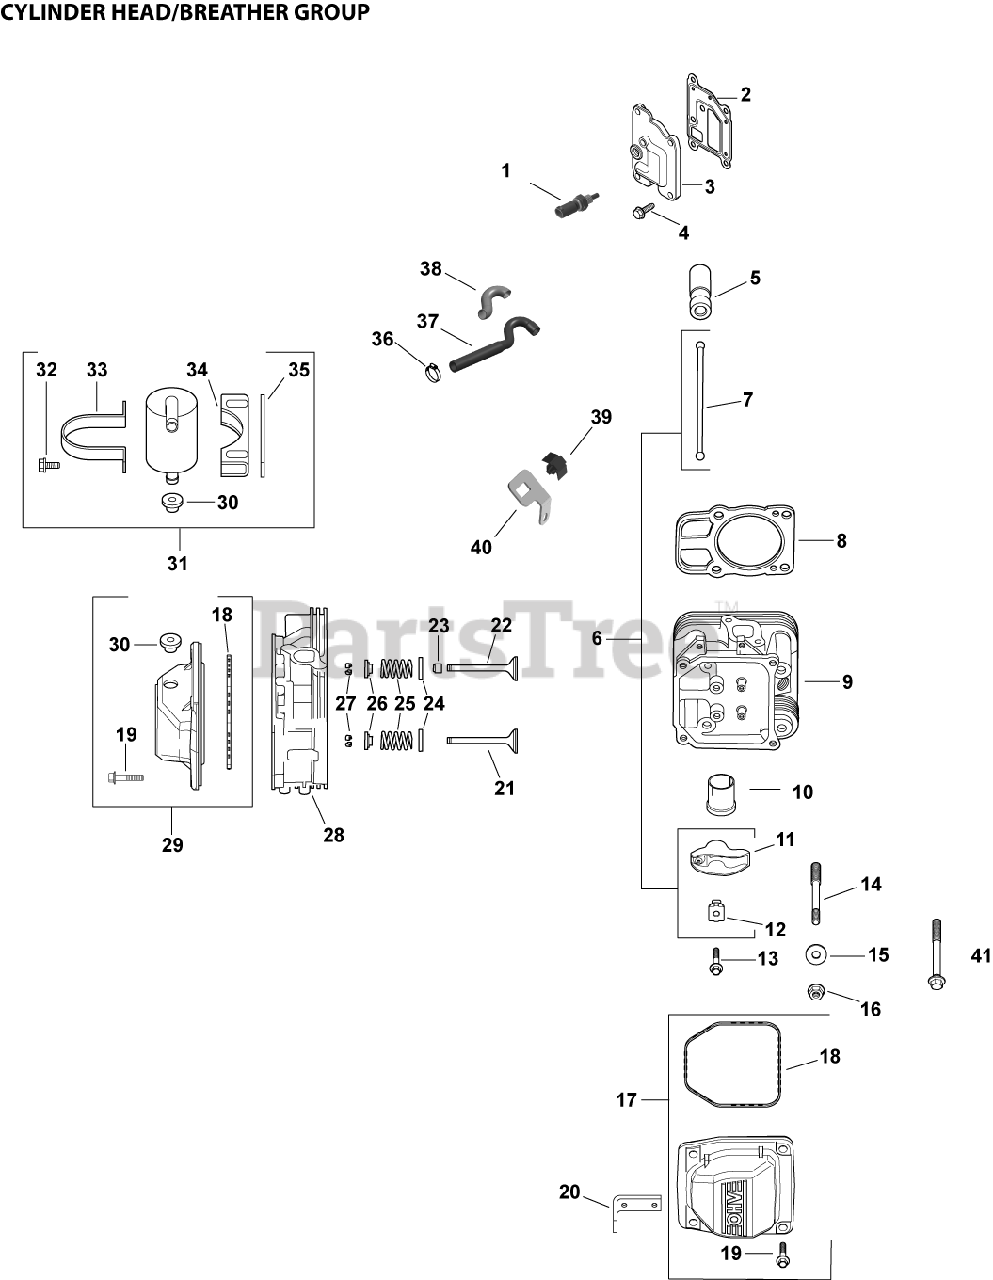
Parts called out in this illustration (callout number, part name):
1	SENSOR, TEMPERATURE
2	GASKET, BREATHER
3	KIT, BREATHER COVER
4	SCREW, THREAD FORMING
5	LIFTER, VALVE HYDRAULIC - (#2535111S)
6	KIT, VALVE TRAIN
7	ROD, PUSH
8	KIT, GSKT CYL HD (C22-23 674CC)
9	KIT, CYLINDER HEAD #2
10	SCREW, THREAD FORMING
11	ARM, ROCKER
12	PIVOT, ROCKER ARM
13	SCREW, FLG M6X1.0X34
17	KIT, VALVE COVER-PLAIN
18	O-RING (YELLOW), VALVE COVER
19	SCREW, FLG M6X1.0X30
20	STRAP, LIFT
21	VALVE, EXHAUST
21	VALVE, EXHAUST (.25)
22	VALVE, INTAKE (STD)
22	VALVE, INTAKE (.25)
23	SEAL, VALVE BAND
24	RETAINER, SPRING
25	SPRING, VALVE
26	CAP, VALVE SPRING
27	KIT, RETAINER
28	KIT, CYLINDER HEAD #1
29	KIT, VALVE COVER
30	GROMMET, RUBBER
36	CLAMP, HOSE-USE 25 237 32-S
37	HOSE, BREATHER
38	SLEEVE, ANTI ABRASION 4.4 O.L.-USE 25 431 12-S
39	CLIP, O2 SENSOR
40	BRACKET, OXYGEN SENSOR
41	SCREW, FLG M10X1.5X90
44	KIT, BREATHER SEPARATOR
47	SCREW, HI-LOW
2401805-S	RETAINER, VALVE GUIDE (KM)
